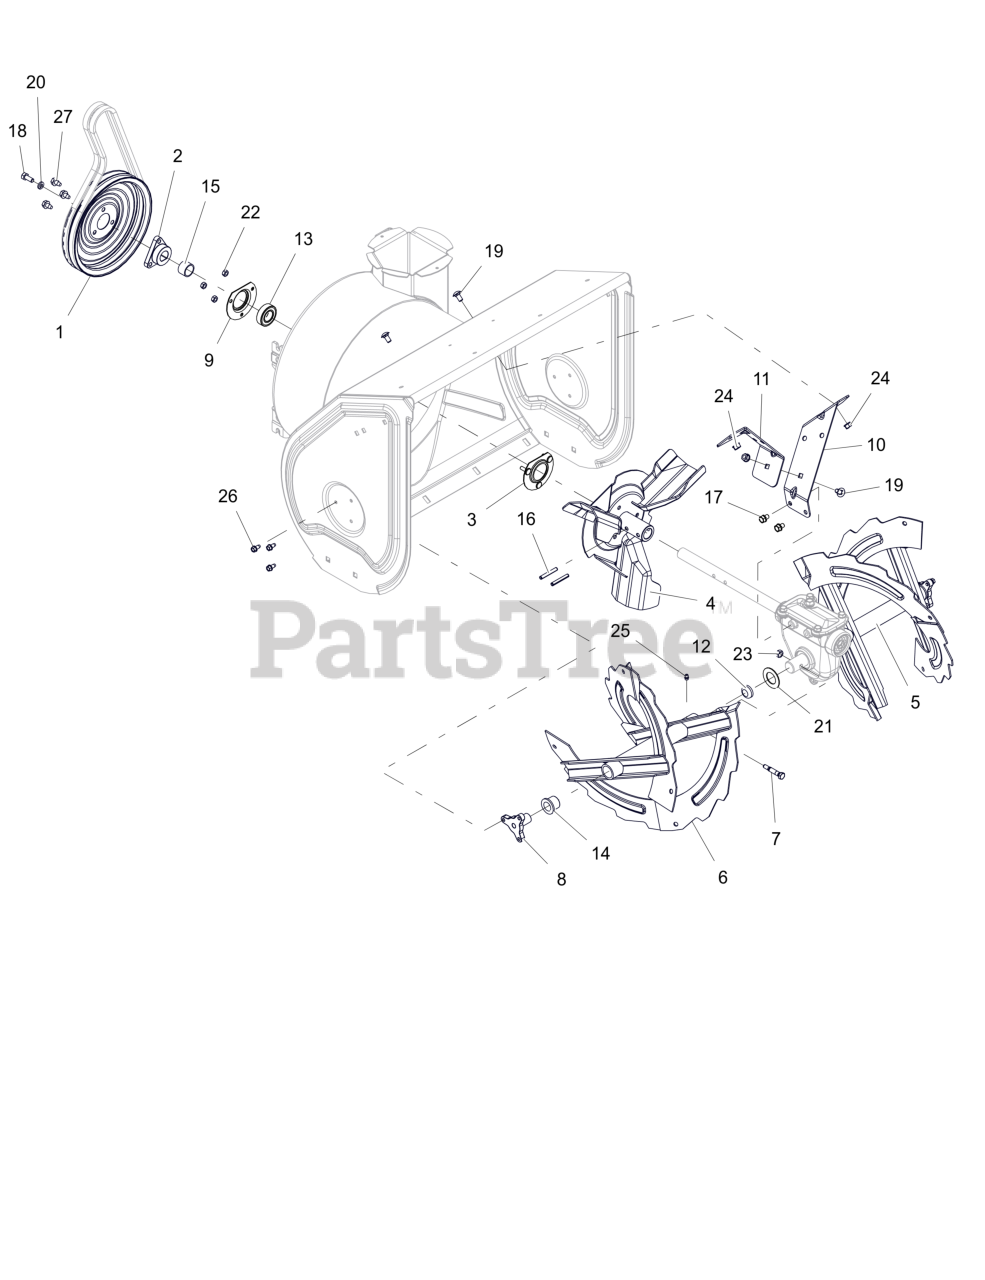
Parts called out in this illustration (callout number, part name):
1	PULLEY, SPIN FORM DUAL GROOVE
2	PULLEY HUB, D-BORE .87 PRO
3	BEARING FLANGE
4	IMPELLER, 3 BLADE-14"
5	RAKE, LH W/ZERK - 24"
6	RAKE, RH W/ZERK - 24"
7	SHEAR BOLT SERVICE ASSEMBLY
8	SUPPORT, RAKE BUSHING
9	BEARING FLANGE
10	BRACKET, GEARCASE SUPPORT - LH
11	BRACKET, GEARCASE SUPPORT - RH
12	PLUG, RAKE TUBE
13	BRG-BALL .876 X 1.750 X .50
14	BSHG-FLG, NY.778 ID X 1.018 OD
15	BSHG,SPCR .895X1.065X.693
16	PIN-ROLL .250X1.75
17	BLT, SEMS .31-18X.50 G5 ZCC
18	BLT, HEX .31-24X.750 G5 ZCC
19	BLT,RHSSN.31-18X.625 G5 ZCCP30
20	WSHR, LK-HVY .312X.097 ZCC
21	WSHR- FLT 1.010X1.755X.062 ZCC
22	NUT,LK-CTR .25-20 GA ZCC
23	NUT,LK-CTR .31-18 GA ZCC
24	NUT-LK-TOP-FLG .312-18 GF ZCC
25	ZERK,FITTING .25X.125 DRIVE IN
26	SCR-TAP .25-20X.50 HWH ZCC
27	SCR,TAP .312-18X.50 HWH TR ZCC
